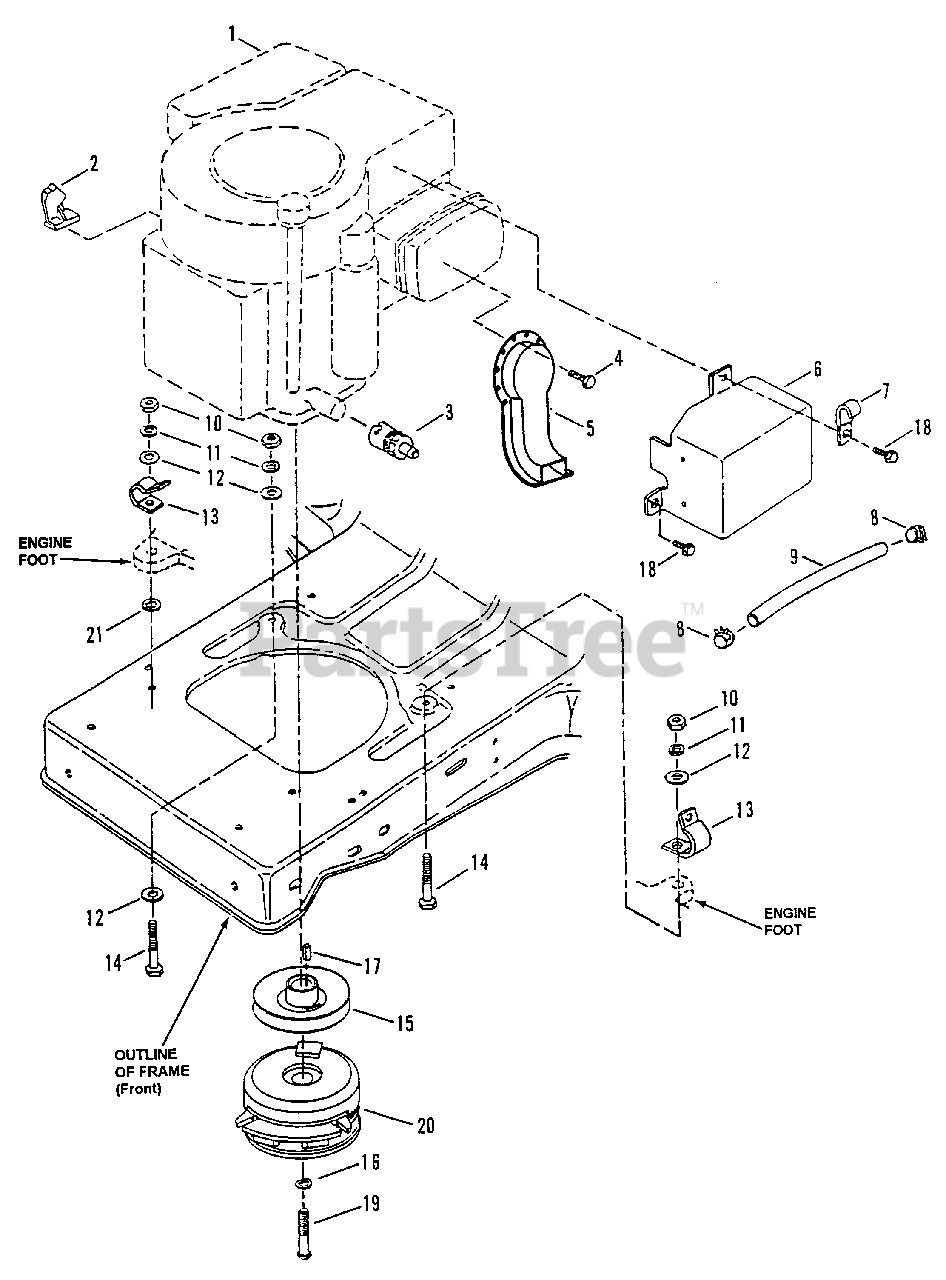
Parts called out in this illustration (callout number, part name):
2	CLIP, Speed
3	ASSEMBLY, Oil Valve
4	SCREW, #8-18 x 1/2" Hex Head, Self-Tapping
5	EXTENSION, Muffler
6	HEAT SHIELD, Muffler
7	CLIP, "J" Type
8	CLAMP, Fuel Line
9	LINE, Fuel, 16" Long
10	NUT, 5/16-18 Hex, Grade 5 or B
11	WASHER, 5/16 Split Lock
12	WASHER, 5/16 Flat
13	CLIP, Wiring Harness
14	SCREW, 5/16-18 x 1-3/4" Hex Head Cap, Grade 5
15	PULLEY, Traction Drive
16	WASHER, 7/16 Split Lock
17	KEY, 1/4 x 1/4 x 3/4" Square
18	BOLT, 1/4-20 x 1/2" Hex Flange Lock, Grade 5
19	SCREW, 7/16-20 x 2-1/2" Hex Head Cap, Special, Grade 5
20	CLUTCH/BRAKE
21	WASHER, 5/16 Internal Tooth Lock
